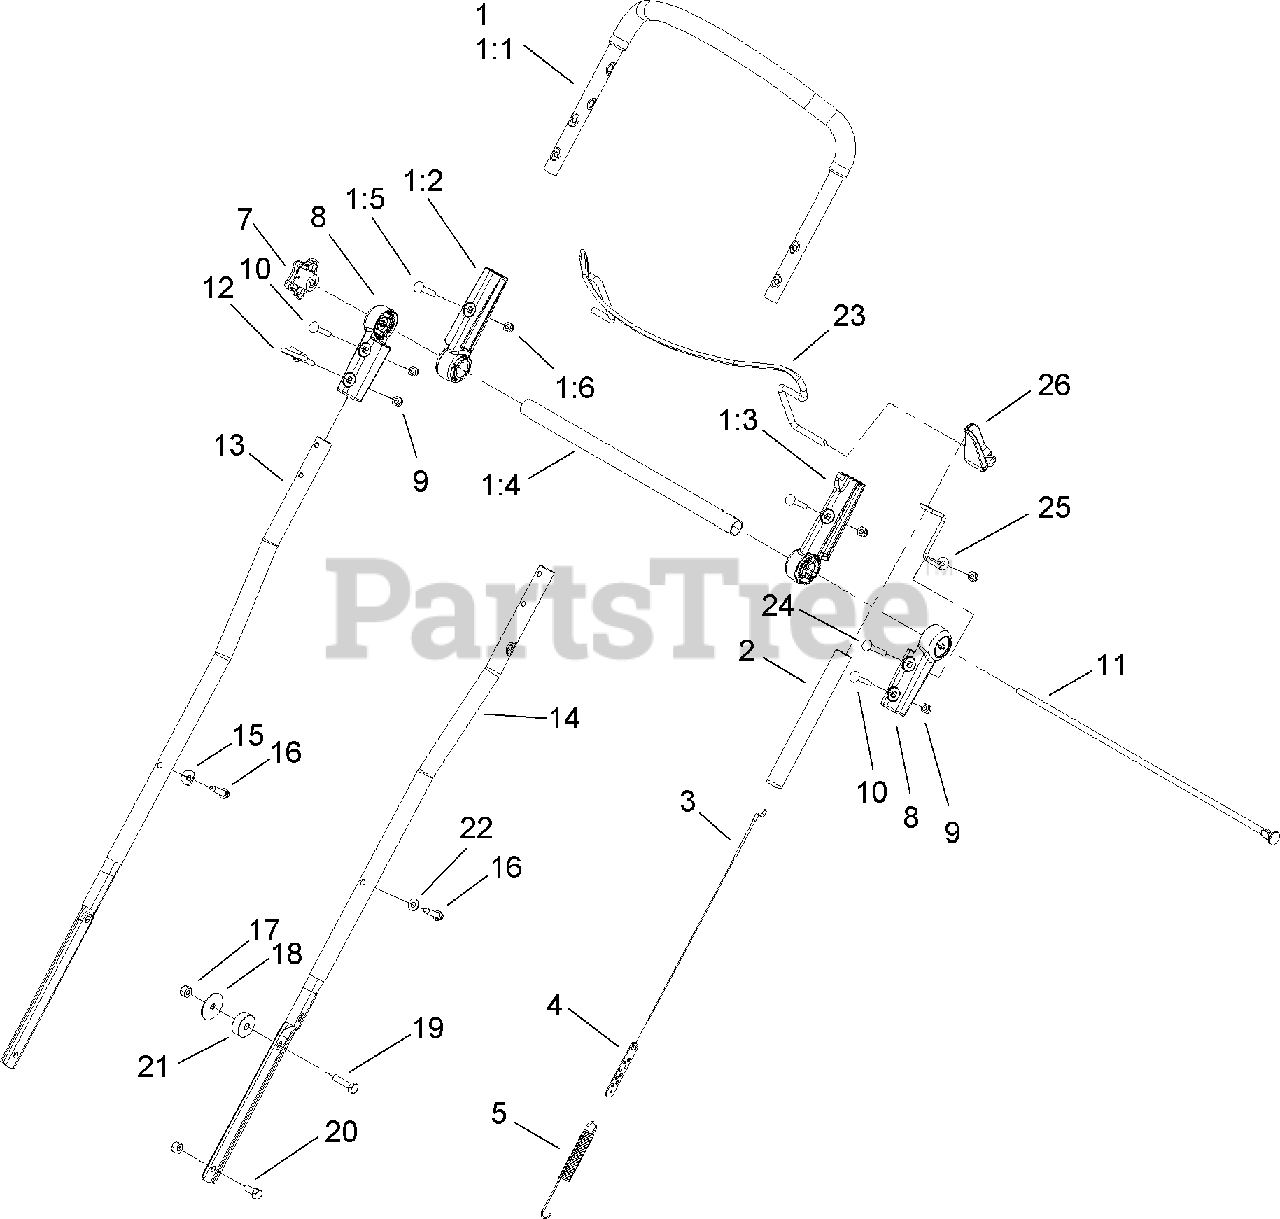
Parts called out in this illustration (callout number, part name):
1	UPPER HANDLE ASM
1:1	HANDLE ASM
1:2	MOUNT-HANDLE, RH
1:3	MOUNT-HANDLE, LH
1:5	SCREW-CARR
1:6	NUT-LOCK, NI
2	COVER-SPRING
3	CABLE-CLUTCH
4	ADJUSTER-CABLE, CLUTCH
5	SPRING-EXTENSION
8	MOUNT-HANDLE, LOWER
9	NUT-LOCK, NI
10	SCREW-CARR
11	ROD-THREADED
12	GUIDE-ROPE, UPPER
13	HANDLE-LOWER, RH
14	HANDLE-LOWER, LH
16	SCREW-HWH
17	NUT-LOCK, NI
18	WASHER-FLAT
19	SCREW-HH
20	SCREW-HH
22	WASHER-FLAT
24	SCREW-CARR
25	GUIDE-ROPE
26	STOP-BAIL
